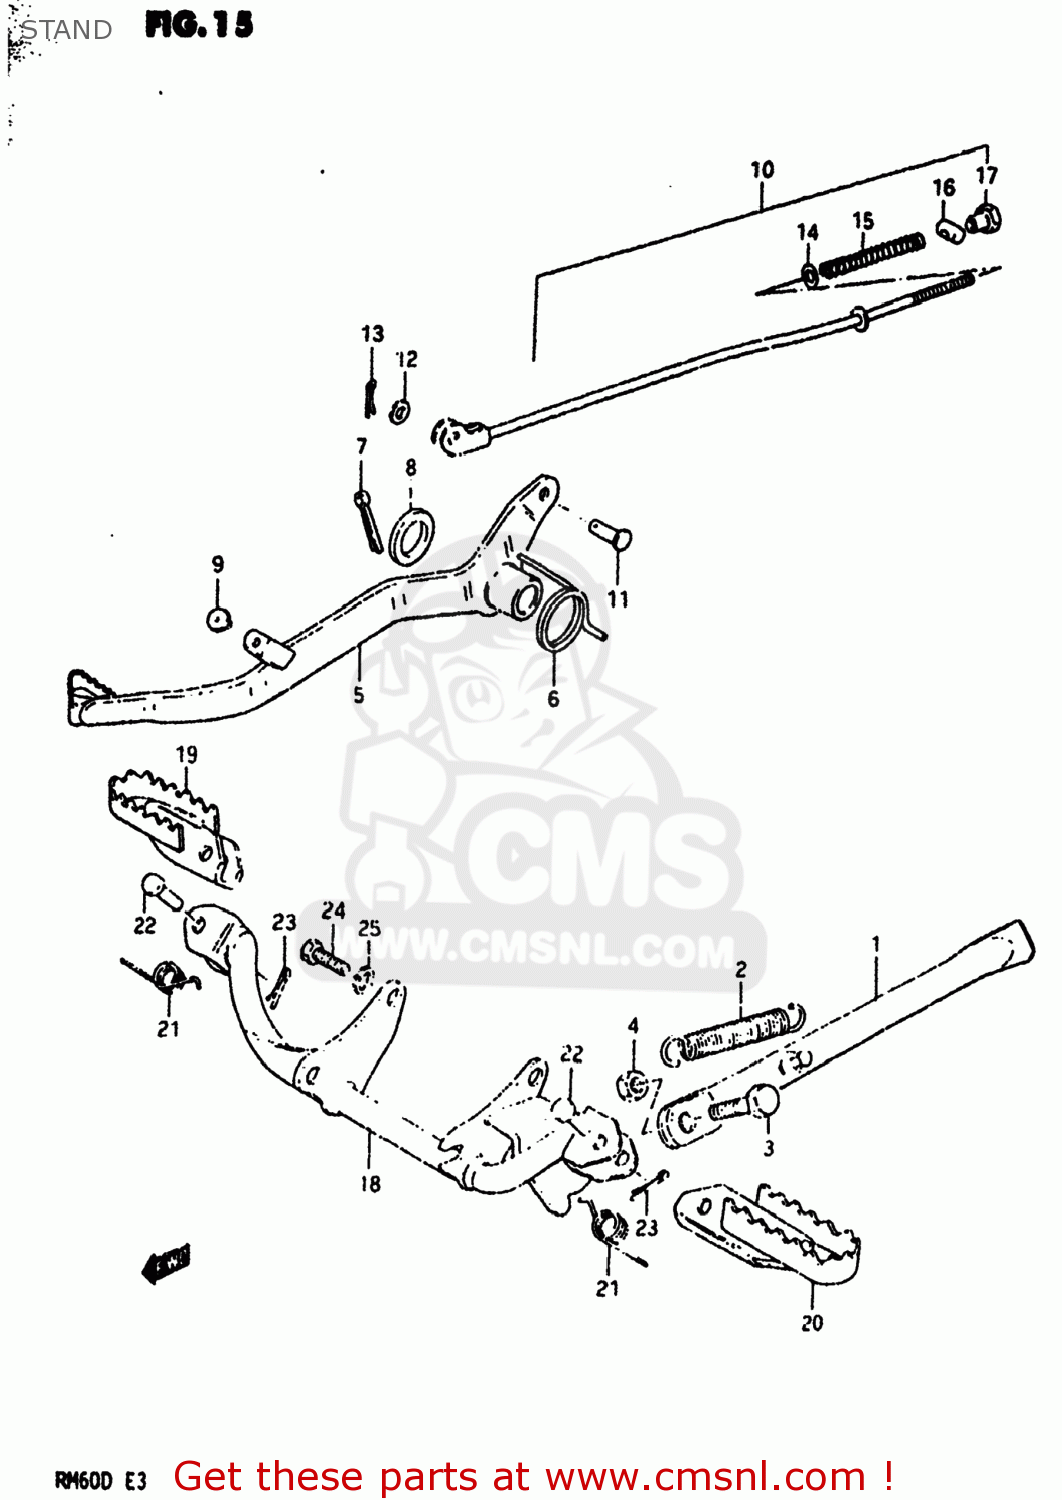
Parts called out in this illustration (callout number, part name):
1	STAND,SIDE
2	SPRING
3	BOLT
4	NUT
5	PEDAL,BRAKE
6	SPRING
7	COTTER PIN
8	WASHER(15.5X26X2.3)
9	STOPPER,BRAKE PEDAL
10	ROD ASSEMBLY,REAR BRAKE
11	PIN(L:13.5)
12	WASHER
13	PIN 20X20
14	WASHER
15	SPRING
16	PIN(11X18)
17	NUT
18	BAR,FRONT FOOTREST
19	FOOTREST,FRONT,RIGHT
20	FOOTREST
21	SPRING
22	PIN
23	PIN 20X20
24	BOLT
25	LOCK WASHER
